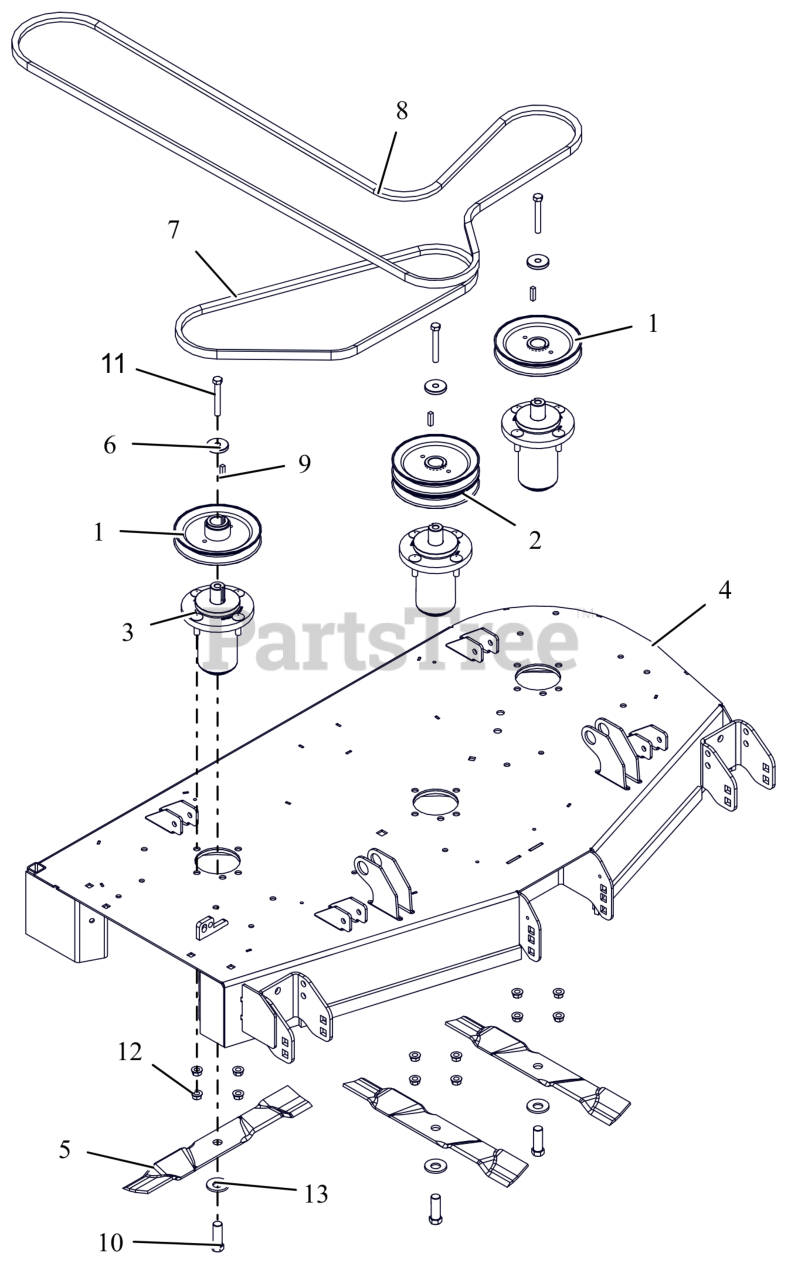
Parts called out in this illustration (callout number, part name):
1	PULLEY, SINGLE-1"ID X 6" OD
2	PULLEY, DOUBLE
3	ASM, MAINT FREE ALUM SPINDLE
4	WLDMT, 48'' CE SIDE DISCH DECK (ORANGE)
5	BLADE, MULCH - 16.25"
6	RETAINER, SHEAVE
7	V-BELT, B-COGGED
8	V-BELT, HB SECTION
9	KEY, SQ .25X.25X1.00 RC 40-50
10	BLT, HEX .62-18X1.75 G8 ZCC
11	BLT, HEX .38-16X2.75 G8 ZCC
12	NUT-LK-CTR-FLG .375-16 GF ZCC
13	WSHR-BLVL .669X1.535X.138
